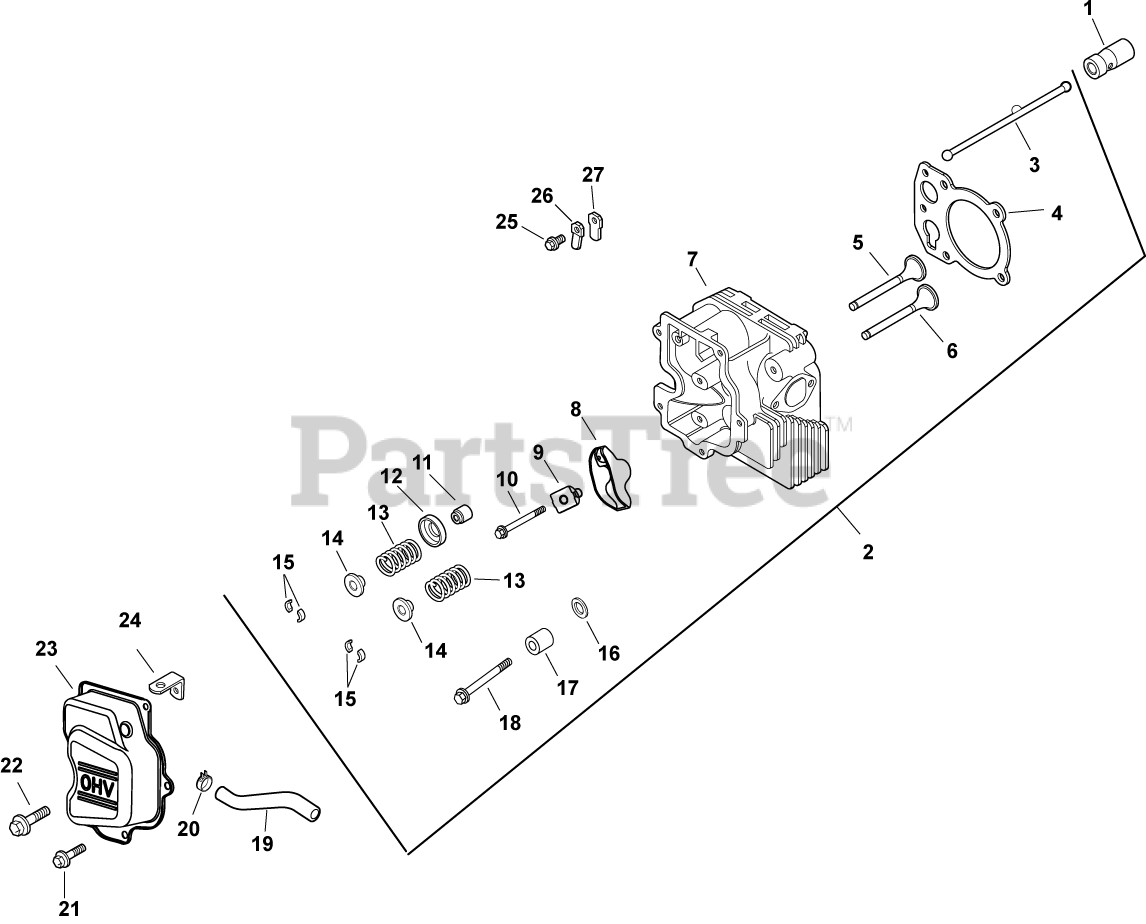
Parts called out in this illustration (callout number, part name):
1	LIFTER, HYDRAULIC VALVE-USE 25 351 10-S
2	KIT, LP CYL HD W/PORT LINER - DISCONTINUED
3	ROD, PUSH
4	GASKET, CYLINDER HEAD
5	VALVE, INTAKE
6	VALVE, EXHAUST
7	HEAD, CYLINDER - DISCONTINUED
8	ARM, ROCKER
9	PIVOT, ROCKER ARM
10	SCREW, FLG M6X1.0X34
11	SEAL, VALVE STEM - (#2503214S)
12	RETAINER, SPRING
13	SPRING, VALVE
14	RETAINER, VALVE SPRING - USE 25 173 28-S
15	KIT, RETAINER
16	WASHER, FLAT 13/32"
17	SPACER - DISCONTINUED
18	SCREW, CYLINDER HEAD (M10 X 80)
19	HOSE, BREATHER
20	CLAMP, HOSE (KM)-USE 25 237 31-S
21	SCREW,FLG THD FRM M6X1.0X16-(#25086397S)
22	SCREW,FLG THD FRM M6X1.0X20-(#25086396S)
23	COVER, ROCKER
25	SCREW, FLG THD FRM M5X.8X10
26	REED, BREATHER
27	RETAINER, REED
